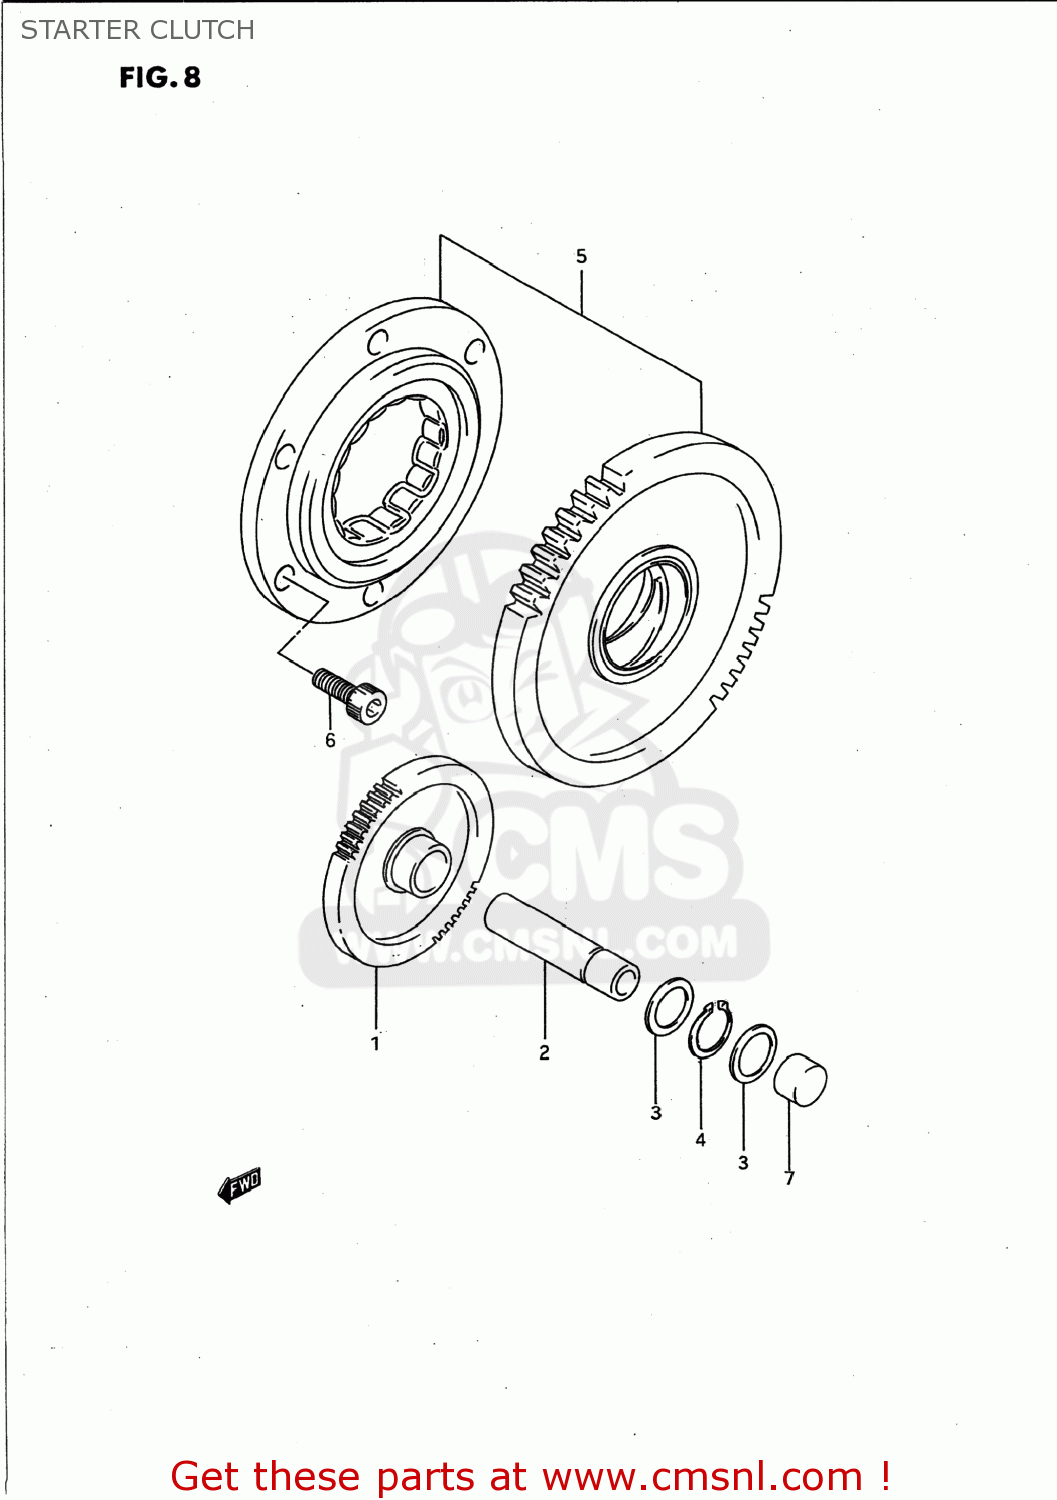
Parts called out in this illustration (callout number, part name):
1	GEAR,STARTER IDLE
2	SHAFT,STARTER IDLE GEAR
3	WASHER
4	CIRCLIP,12 MM
5	CLUTCH SET,STARTER
6	BOLT
7	PLUG
